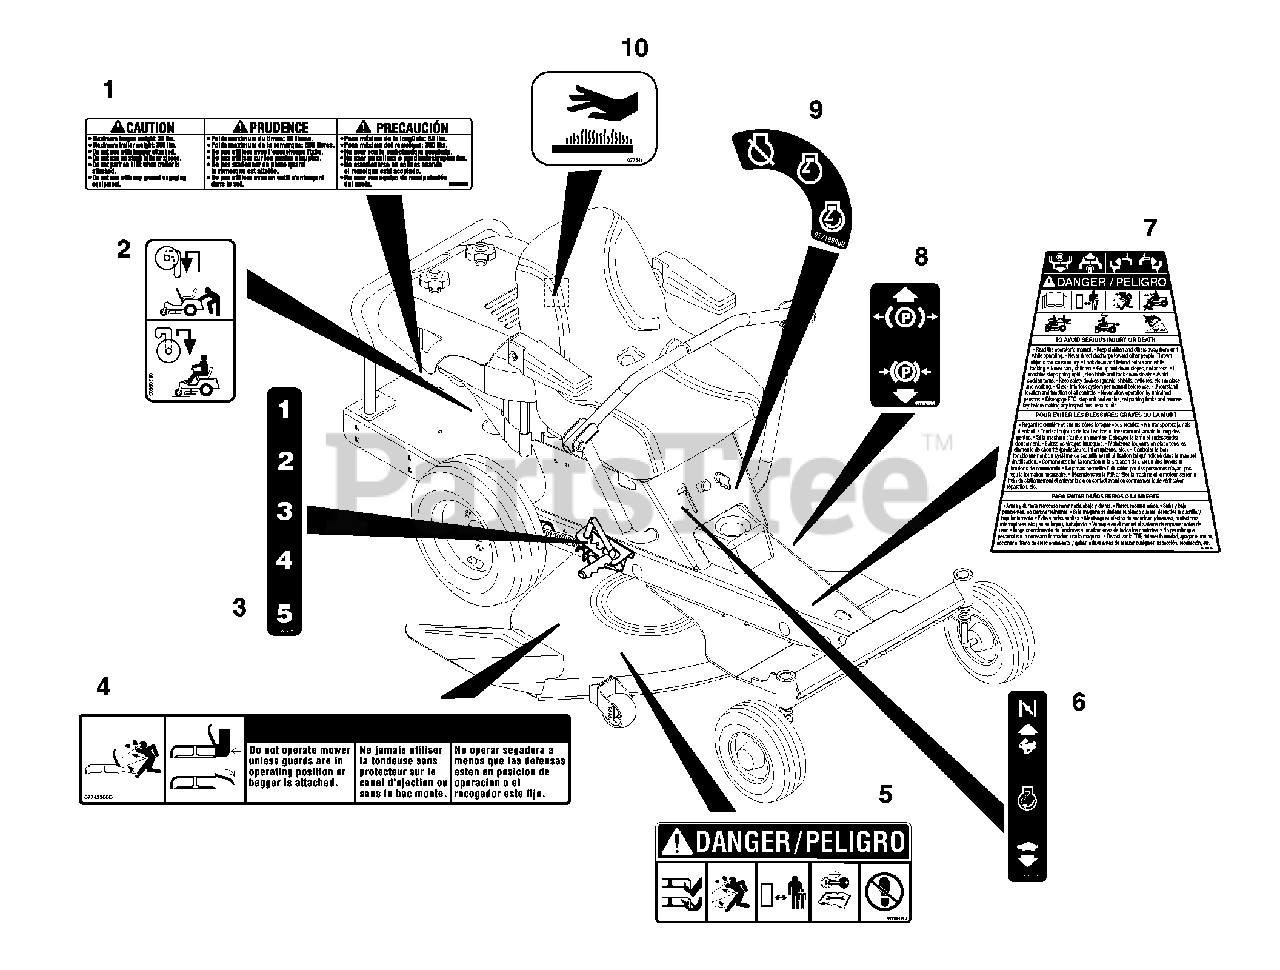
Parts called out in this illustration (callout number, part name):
1	Decal, Trailer Hitch
2	Decal, Transmission Disconnect
3	Decal, Deck Lift
4	Decal, Warning
5	Decal, Mower Pan Danger
6	Decal, Throttle
7	Decal, Sport Zoom Warning
8	Decal, Parking Brake Lever
9	Decal, Ignition
10	Decal, Hot Surface
